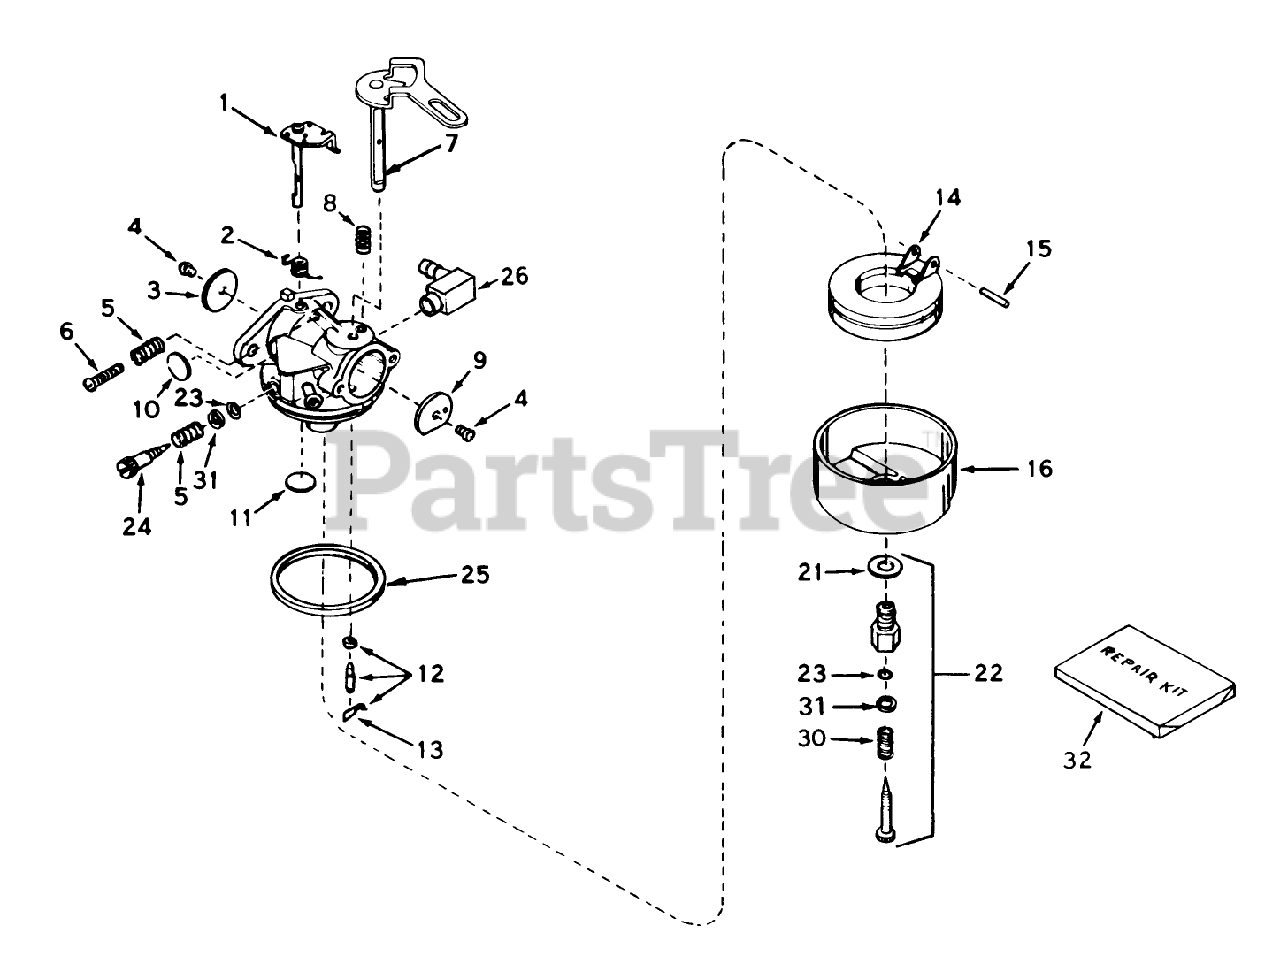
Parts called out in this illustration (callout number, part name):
1	Throttle Shaft and Lever ASM
2	Spring-Return, Throttle
3	Shutter-Throttle
4	Screw-Shutter
5	Spring-Tension
6	Screw-Throttle Crack Screw / Idle Speed
7	Choke Shaft and Lever Asm
8	Spring-Positioning, Choke
9	Shutter-choke
10	Plug-Welch, Idle Mixture Well
11	Plug-Welch, Atmospheric Vent
12	Inlet Needle, Seat Clip Assy. (Incl. No. 13)
13	Clip-Spring
14	Float
15	Shaft-Float
16	Bowl-Float (no drain)
21	Washer-Bowl Nut
22	Adjustment Screw Assy., Main (Incl. Nos. 5A, 21 23)
23	ORing
24	Screw, Idle Adj.
25	O Ring-Bowl, Float
26	Fitting-Fuel
30	Spring
31	Washer
32	Repair Kit (Incl. items marked *)
